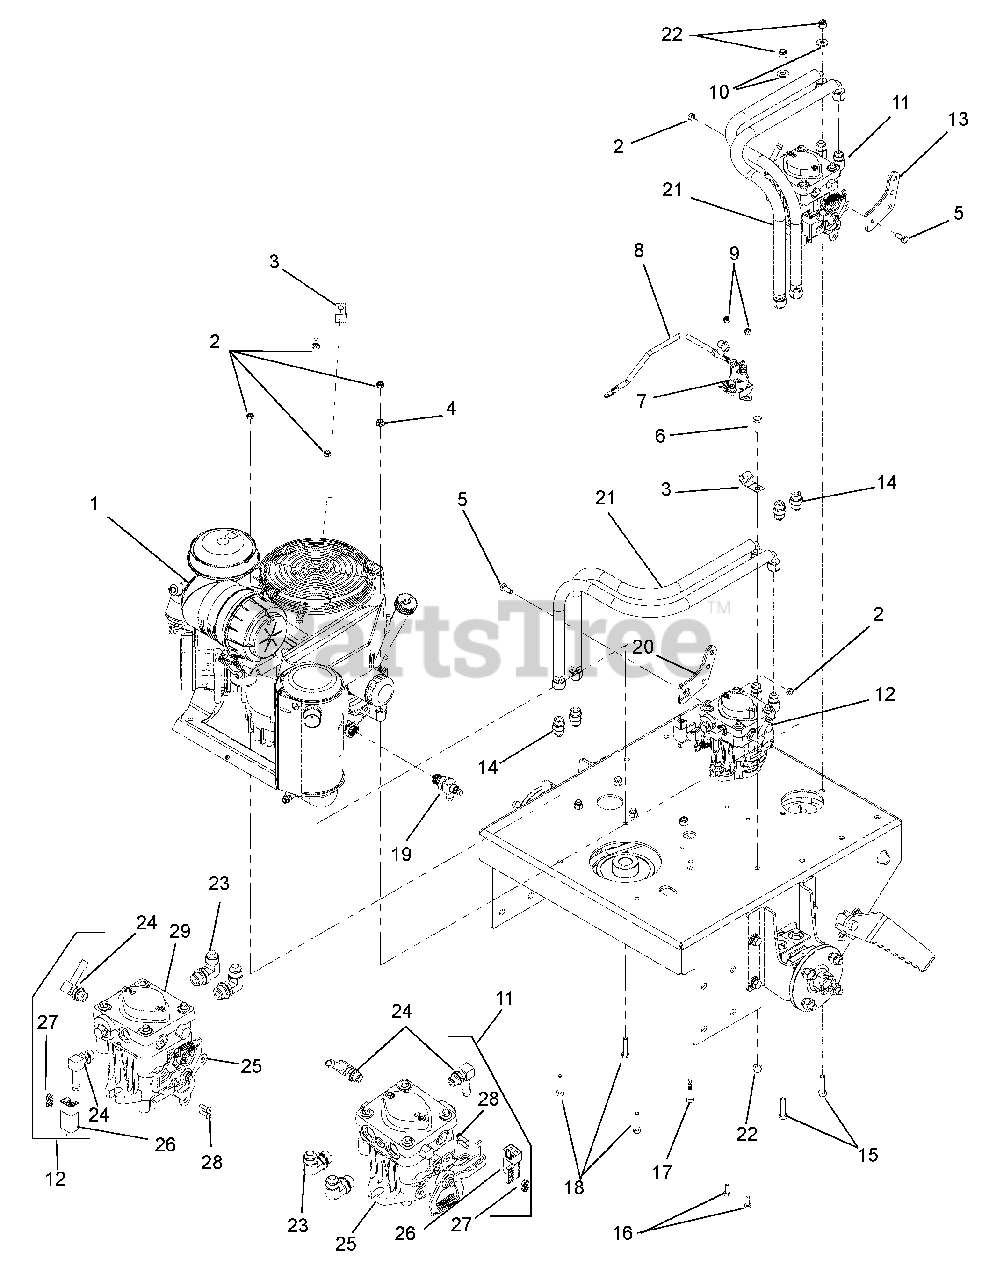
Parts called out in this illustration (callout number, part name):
1	ENGINE, KAWASAKI 19HP FH580V
2	LOCKNUT, 5/16-18 NYLOC Y
3	P-CLIP, .500 INSULATED
4	LOCKNUT, 5/16-18 WHIZ Y
5	BOLT, 5/16-18 X .750 HEX 5 Y
6	BOLT, 3/8-16 X 1.00 HEX 5 Y
7	SOLENOID, 12 V STARTER
8	CABLE, 12" STARTER
9	LOCKNUT, 1/4-20 NYLOC Y
10	WASHER, .313 REG FLAT Y
11	ASSY, LH PUMP WALKBEHIND (INCLUDES ITEMS 23, 24, 26 – 28)
12	ASSY, RH PUMP WALKBEHIND (INCLUDES ITEMS 23 – 29)
13	WLDT, CSWS LH HYDRO PUMP ARM
14	FITTING, STRAIGHT
15	BOLT, 3/8-16 X 1.50 HEX 5 Y
16	BOLT, 1/4-20 X .750 HEX 5 Y
17	BOLT, 5/16-18 X 1.75 HEX 5 Y
18	BOLT, 5/16-18 X 1.50 HEX 5 Y
19	OIL DRAIN FITTING
20	WLDT, CSWS HYDRO PUMP ARM
21	HOSE, HYD 1/2 X 26 1/2 EZFLEX
22	LOCKNUT, 3/8-16 NYLOC Y
23	FTG, ADP JIC-ORB 6801-08-08
24	FTG, 90 9/16 MOR X 3/8 HOSE
25	PUMP, HYD - PG-1HDA-D41X-XXXX RH
26	SWITCH, PLUNGER DP - N.O. - N.C.
27	LOCKNUT, 10-24 NYLOC Y
28	SCREW, 10-24X.625 PAN PHL MACY
29	PUMP, HYD - PG-1KDA-D61X-XXXX LH
